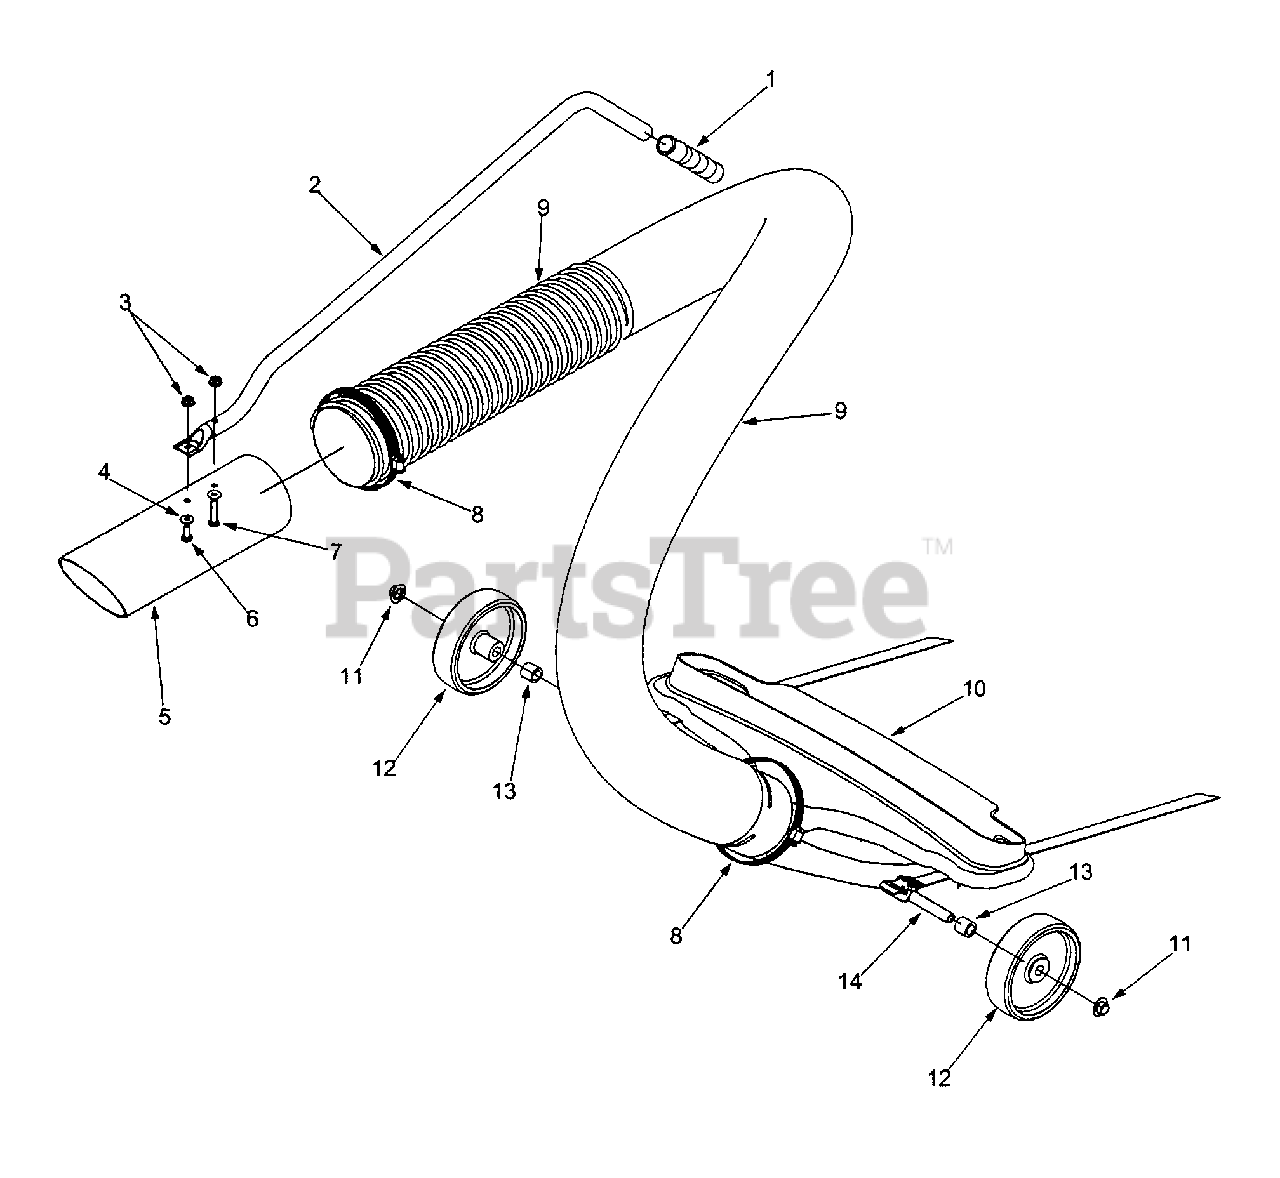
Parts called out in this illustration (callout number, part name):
1	Handle Grip
3	Hex Lock Nut 1/4-20
4	Flat Washer .271 ID x .630 OD
5	Nozzle 3.875 x 12.0
6	Hex Cap Screw 1/4-20 x .620
7	Hex Cap Screw 1/4-20 x 1.25
8	Adjustable Clamp
9	Vacuum Hose
10	Hose Attachment Nozzle Ass'y
11	Push Cap
12	Wheel 5.0 x 1.38
13	Spacer
14	Axle .50 OD x .354 ID x 16.7
